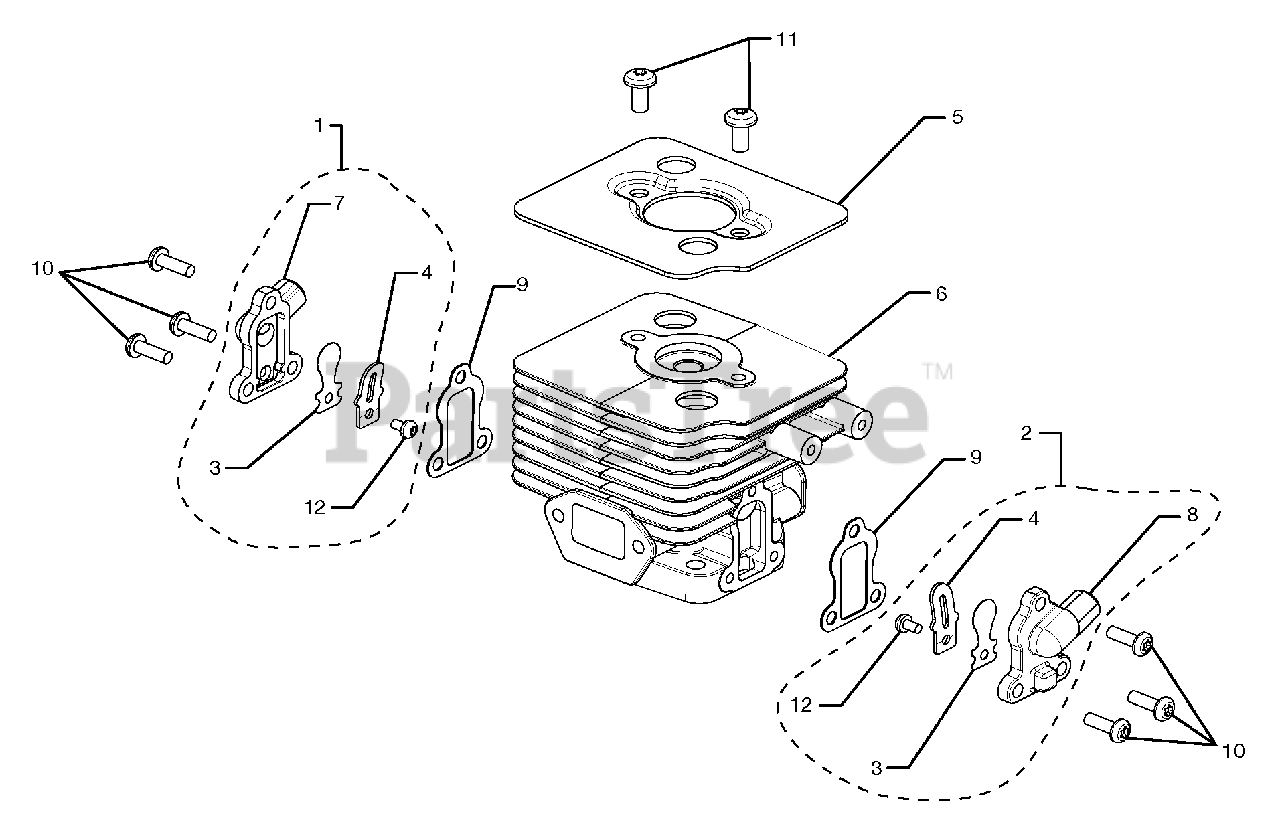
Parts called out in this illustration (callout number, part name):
1	Start Side Reed Valve Assembly
2	Flywheel Side Reed Valve Assembly
3	Stamping Petal Reed Valve
4	Stamping Stop Reed Valve
5	Cylinder Plate
6	Stratified Cylinder
7	Starter Side Cover Valve
8	Flywheel Side Cover Valve
9	Reed Valve Cover Gasket
10	Screw
11	Screw
12	Screw
